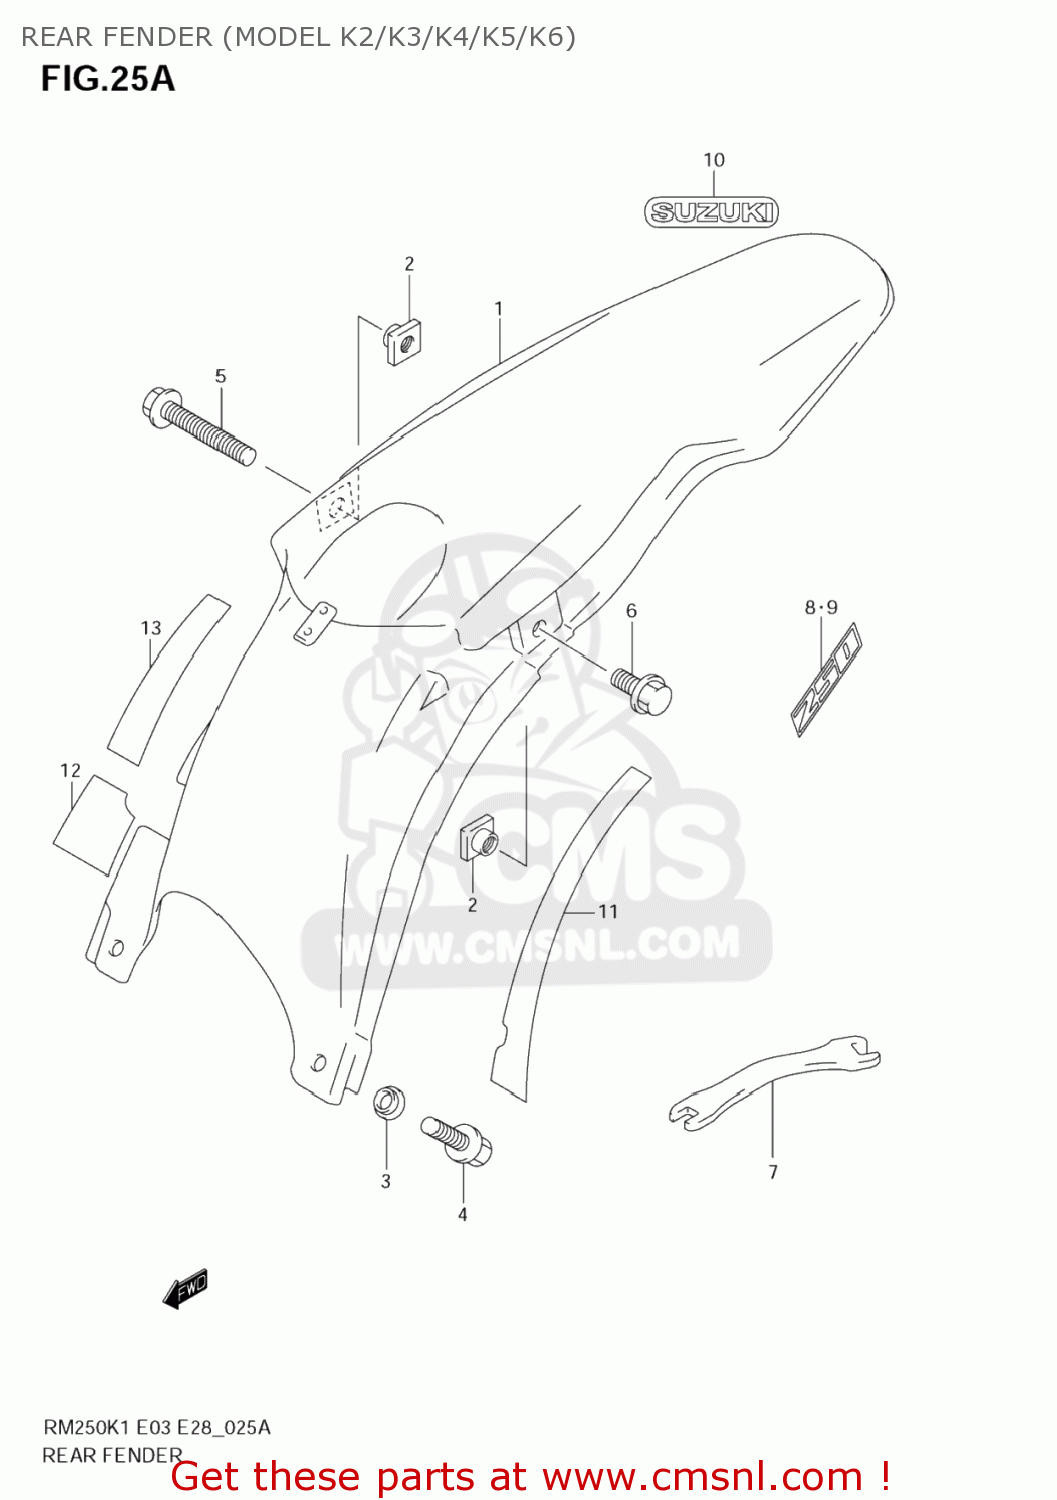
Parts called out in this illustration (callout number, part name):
1	FENDER,RR
2	NUT
3	WASHER
4	BOLT,6X20
5	BOLT(6X35)
6	BOLT(6X16)
7	SPANNER,OPEN
8	TAPE,RR FENDER,R
9	TAPE,RR FENDER,L
10	EMBLEM,RR
11	CUSHION,RR FENDER NO.1
12	CUSHION,RR FENDER NO.2
13	CUSHION,RR FENDER NO.3
